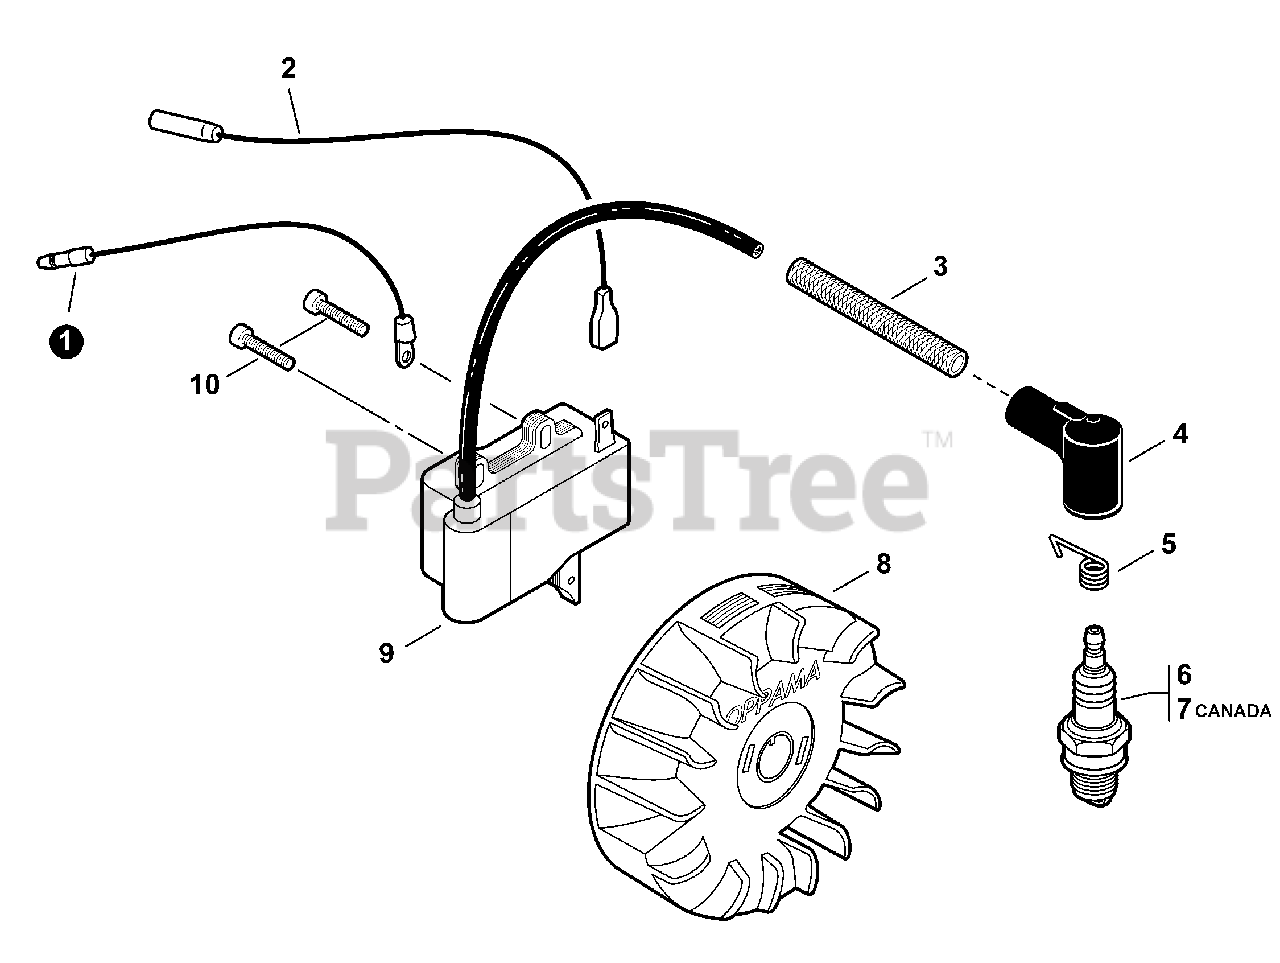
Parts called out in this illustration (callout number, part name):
1	LEAD - GROUND
2	LEAD - IGNITION
3	TUBE, INSULATOR
4	CAP, SPARK PLUG
5	TERMINAL, SPARK PLUG
6	SPARK PLUG - BPM8Y
7	SPARK PLUG - BPMR8Y
8	FLYWHEEL
9	COIL, IGNITION
10	BOLT 4×20
